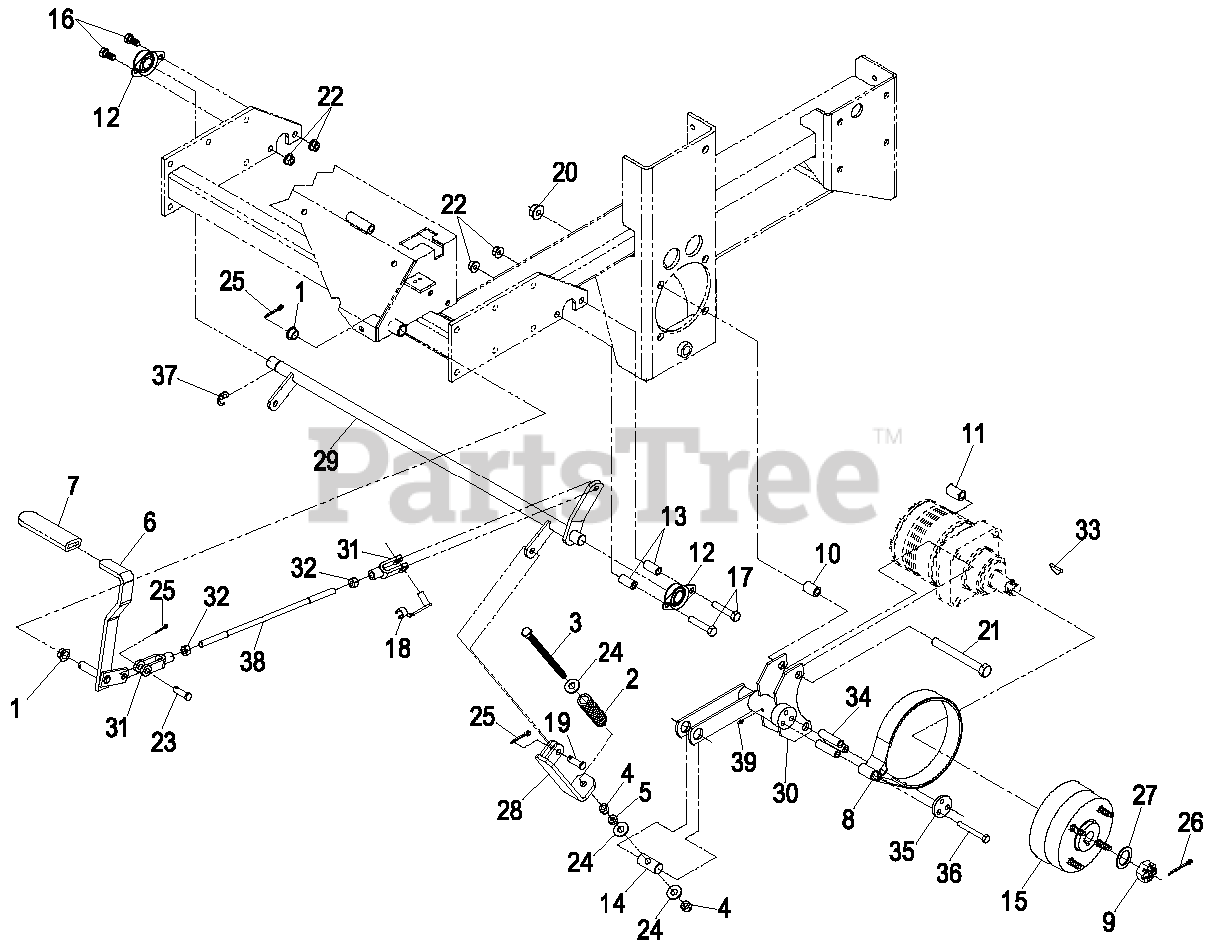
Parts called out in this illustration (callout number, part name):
1	BEARING-CONTROL
2	SPRING-COMPRESSION
3	BOLT-TAP, HH
4	NUT-LOCK, NI
5	NUT-JAM
6	BRAKE LEVER AND GRIP ASM
7	GRIP-LEVER
8	BAND,BRAKE
10	SPACER-WHEEL, SHORT
11	SPACER-WHEEL, LONG
12	BEARING-FLANGE, SIDE
13	SPACER-RETAINER, BRAKE
14	PIN-TRUNION
15	WHEEL HUB ASM
16	SCREW-HH
17	SCREW-HH
18	PIN-SPRING, CLEVIS
19	PIN-CLEVIS
20	NUT-HHF
21	SCREW-HH
22	NUT-HHF, WHIZ
23	PIN-CLEVIS
24	WASHER-FLAT
25	PIN-COTTER
26	PIN-COTTER
27	WASHER-SPACER
28	LINKAGE-BRAKE, LOWER
29	SHAFT-BRAKE
30	BRAKE-NARROW
31	YOKE-LINKAGE, BRAKE
32	NUT-HEX
33	KEY-WOODRUFF
35	RETAINER-BAND, BRAKE
36	SCREW-HH
38	ROD-BRAKE
39	FITTING-GREASE
